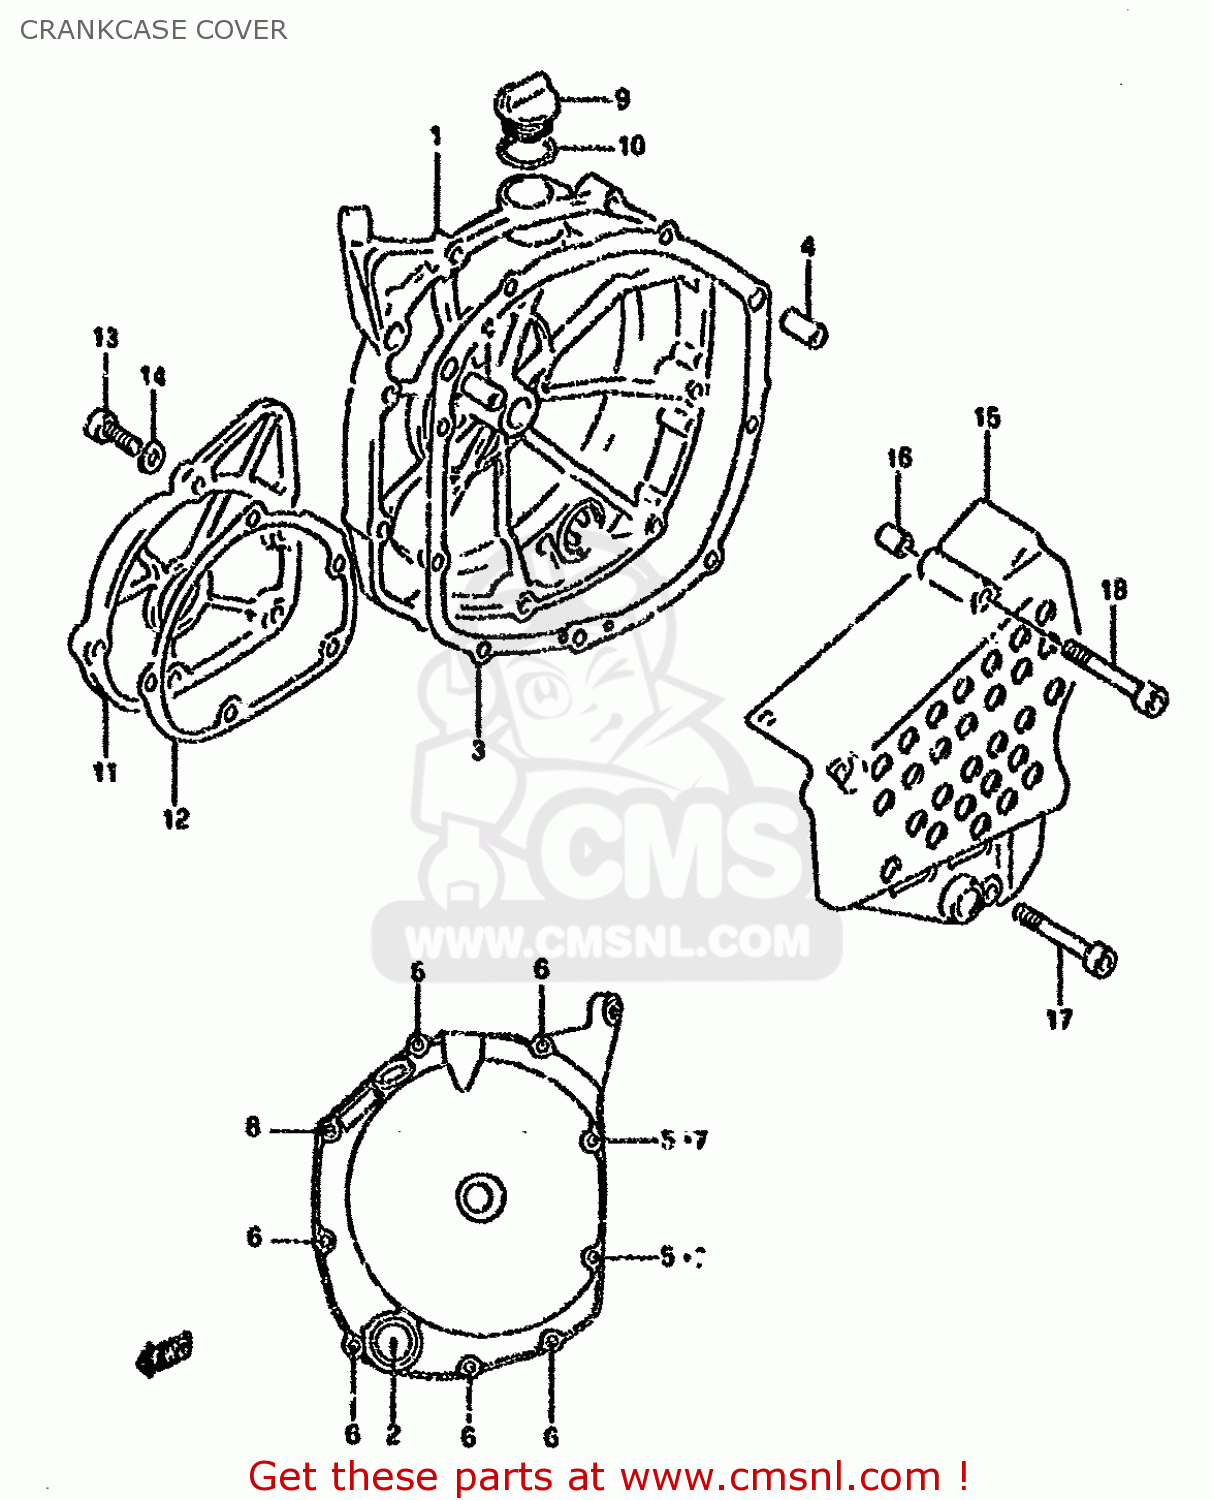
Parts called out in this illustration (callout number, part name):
1	COVER,CLUTCH
2	LENS,OIL LEVEL CHECK
3	GASKET,CL COVER (NAS)
4	PIN
5	GASKET(5.8X11X1.2) (NAS)
6	BOLT
7	BOLT
8	BOLT
9	PLUG
10	O RING(D:3.1,ID:16.8)
11	CAP
12	GASKET,SIGNAL GEN COVER
13	BOLT
14	GASKET(5.8X11X1.2) (NAS)
15	COVER,SPROCKET
16	PIN
17	BOLT
18	BOLT
